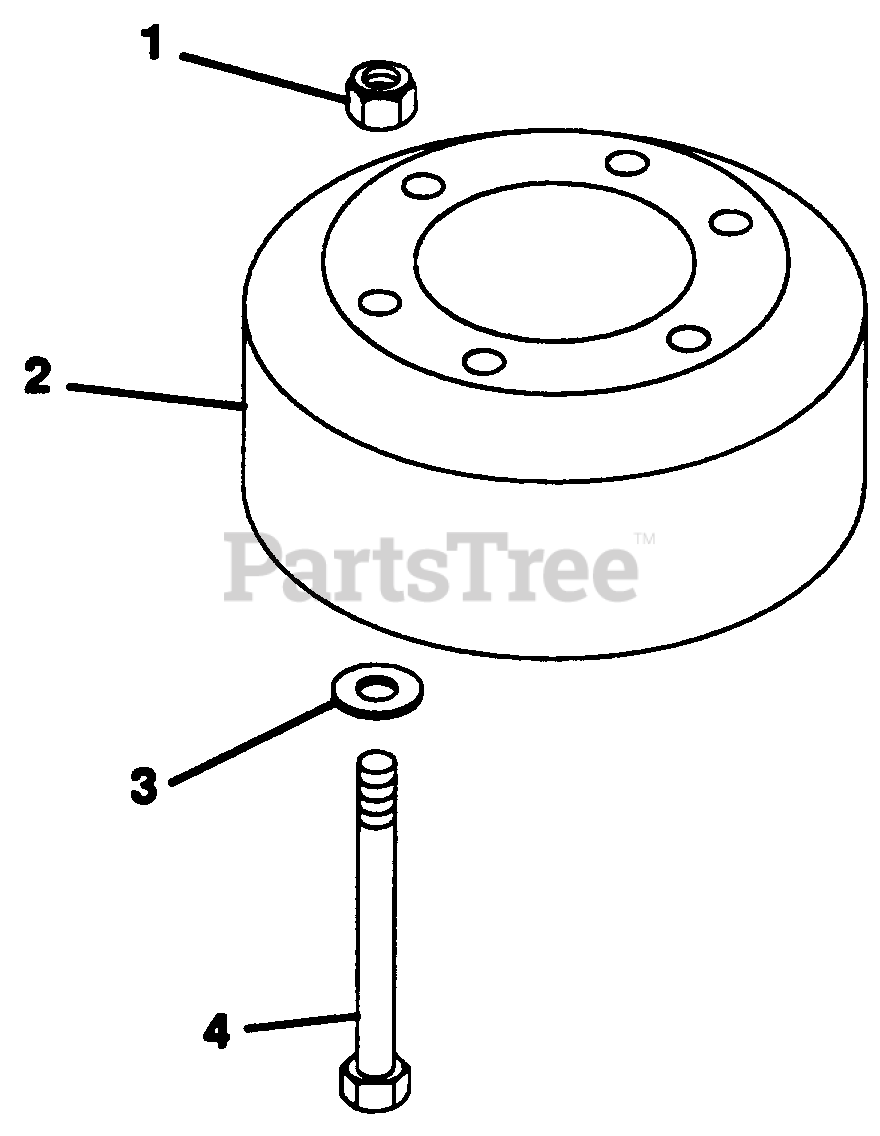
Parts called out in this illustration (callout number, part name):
1	Nut, Lock 1/2-13
2	Weight, 30" Mower
3	Washer, Flat .563x1.375x.109
4	Blot, Hex 1/2-13x4.00
